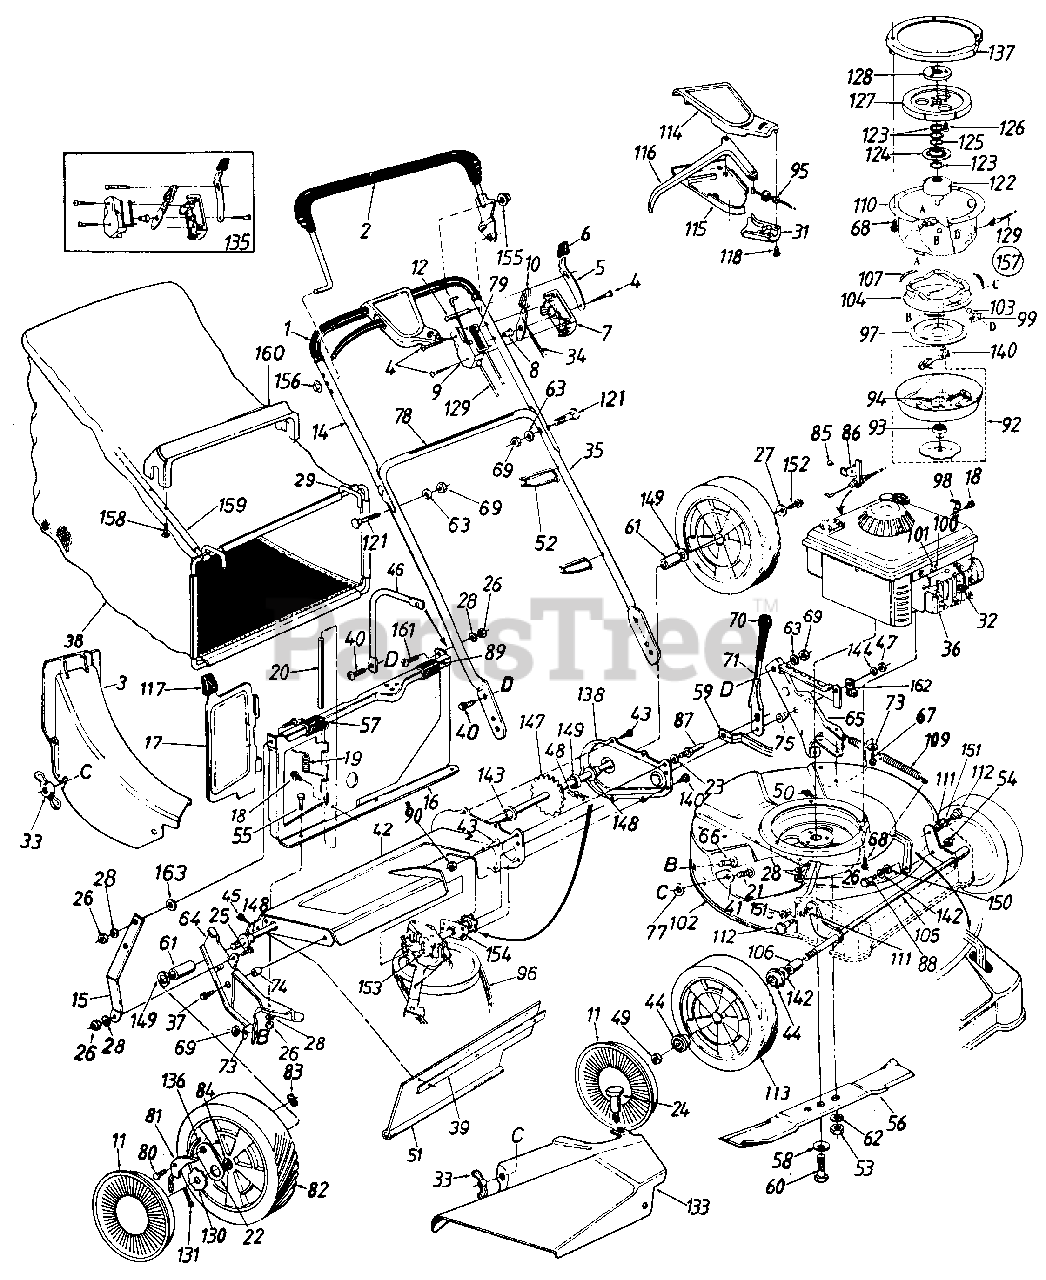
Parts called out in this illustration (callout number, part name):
1	GRIP-FOAM
3	CHUTE ASSY BLACK
4	SCREW-TRUSS MACH
5	SPRING-LOCKOUT
6	KNOB
7	PANEL HALF-CONTROL
8	PIN-CONTROL DISC
9	PANEL HALF-CLUTCH
10	LEVER-THROTTLE CONT-REV
11	HUB CAP
12	PIN-LOCKING
14	HANDLE-UPPER
18	SCREW-HEX B-TAP #10 x .38
19	SPRING-TORSION
21	BOLT-CARRIAGE 1/4-20 x .62
22	PLATE-PAWL
23	WASHER-LOCK-3/8
24	SCREW-SHLD
25	SCREW-HEX 1/4-20 C .62
26	NUT-HEX 1/4-20
27	WASHER-SPRING BELL
28	LOCK WASHER 1/4 DIA
31	COVER-SP CONTROL
32	INSULATOR-SPARK PLUG
33	NUT-WING
34	WIRE-THROTTLE 58 LG
35	HANDLE-LOWER PAINTED
37	SCREW-HEX R
38	BAG-GRASS-BLACK
39	STRIP-RETAINING
40	SCREW-TRUSS MACH 5/16-18 x .75
41	WASHER-FL-.344 ID x .62 OD x .033
44	BEARING-BALL
45	SCREW-HEX WASH HD
46	ARM-CATCHER SUPPORT
47	NUT-HEX LOCK 3/8-24
48	#48 CHAIN 1/2 PITCH
49	NUT-HEX INS L-1/2-20
52	TIE-CABLE
53	NUT-HEX 3/8-24
54	NUT-HEX CENTER L-JAM
55	SCREW-HEX 1/4-20 x .50
56	BLADE-21IN
57	SCREW-TRUSS MACH
58	WASHER-BELL
59	ARM-HGT ADJ CONNECT
60	SCREW-HEX 7/16 N.F. x 2 GR.5
61	SPACER-.513 ID x .703 OD x .69
62	WASHER-LOCK-3/8
63	WASHER-LOCK-5/16
64	BRACKET ASSY-HDLE-RH
65	BRACKET ASSY-HDLE-LH
66	BOLT-CARRIAGE 5/16-18 x .62
67	SCREW-HEX WASH HD 5/16-18X1/2
68	SCREW-HEX HD TAP
69	NUT-HEX 5/16-18
71	LEVER-HGT ADJ
73	WASHER-BELL .337 x .867 x .057
74	SPACER
75	SPACER-SHLD .500 x .100
77	RETAINER-BOLT 1/4X.50 OD
80	SCREW-SHLD .342 DIA x .268
81	PAWL
82	WHEEL ASSY W/TIRE
83	NUT-FLAT WELD 1/4 x 20
86	BRACKET-CABLE
87	PIN-SHLD 3/8-24X1.43 LG
88	SCREW-SHLD .500 DIA x .295
89	CLIP-PANEL BAG
90	NUT-HEX JAM 3/8X24
92	HOUSING-CLUTCH BLADE
93	BEARING-BALL
95	CABLE-CLUTCH
96	BELT-V 3/8 x 31.0
97	CONE-CLUTCH
98	CLAMP-CASING
99	BALL-BLOCK
100	SCREW-HEX WASH HD TAP
101	CLIP-CASING
102	DECK ASSEMBLY-21IN
103	BALL-STEEL
104	CONE-BRAKE CUP
105	AXLE ASSY
107	SPRING-EXTENSION
109	SPRING-EXTENSION
110	HOUSING-CLUTCH
111	WASHER-INTERN L 3/8 X.56 OD x .018
112	SCREW-SHLD
113	WHEEL ASSY W/TIRE
114	COVER-SP CONTROL
115	COVER-HALF CONT-LWR
116	LEVER-CONTROL
117	KNOB
118	SCREW-FL C-SUNK AB
121	BOLT-CARRIAGE-CURV 5/16-18 x 1.38
122	ADAPTER-FIXED PULLEY
123	WASHER-SERRATED
124	PULLEY-MOVABLE
125	WASHER-WAVE
126	SCREW-FL HD TORXB 1/4X20 x .62
128	ADAPTER-FLYWHEEL
129	CABLE-CLUTCH 49 IN
130	RATCHET
131	PIN-COTTER-1/8 DIA x 1.00
133	DEFLECTOR-SIDE CHUTE
135	KIT-THROTTLE CONTROL
136	SPRING-NYLON
137	PLATE-ENGINE MTG
142	WASHER-FL-.510 ID x .75 OD x .033
143	BEARING-HEX FLANGE
144	WASHER-FL-.385 ID x .87 OD x .06
147	SHAFT ASSY-REAR
148	BEARING-HEX FLANGE .506 ID
149	WASHER-FL-.531 x .930 OD x .050
150	WASHER-BELL .505 ID x 1.00 OD
151	BEARING-NYLINER
152	SCREW-1/4-20 x .62
153	TRANSMISSION-COMP
154	BEARING-CUP HEX
156	NUT-SPEED
157	CLUTCH ASSY-BLADE
158	SCREW-HEX AB-TAP
160	HANDLE-BAG-BLACK
161	SCREW-TRUSS MACH
163	WASHER-FL-.285 ID x 1.25 OD x .060
